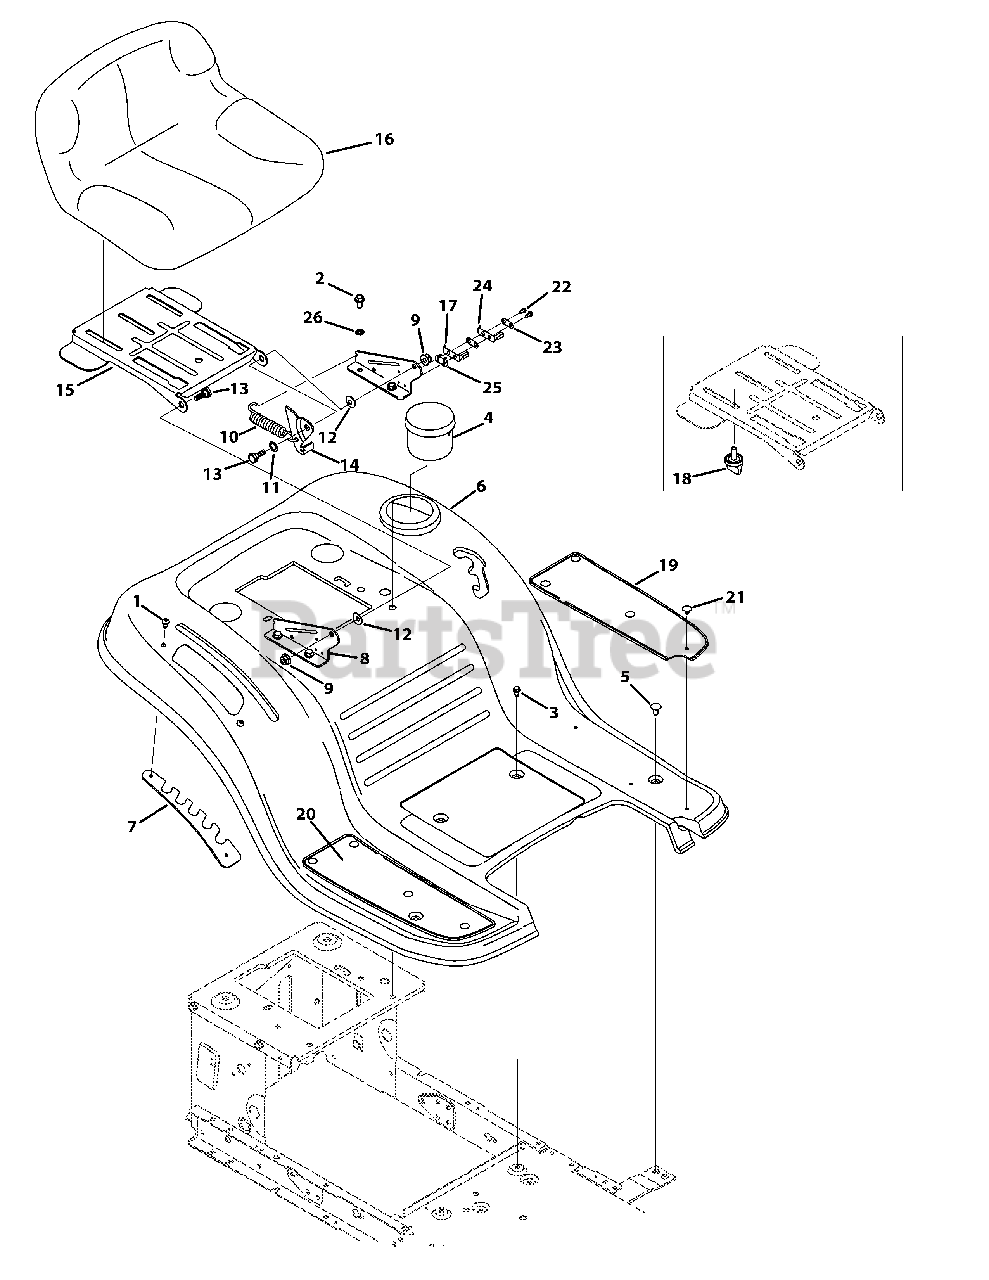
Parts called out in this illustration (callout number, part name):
1	Screw, 1/4-20 x .500
2	Screw, 5/16-18 x .750
3	Screw Pan Torx Head, 1/4-20 x .500
4	Cup Holder
5	Screw Carriage, 1/4-20 x .62
6	Fender - Orange
7	Lift Adjuster Bracket - Powder Black
8	Seat Mount Bracket - Powder Black
9	Flangelock Nut, 5/16-18
10	Extension Spring
11	Flat Washer, .510x .750 x .033
12	Bell Washer, .340 x .872 x .060
13	Shoulder Screw, 5/16-18 x .437 x .268
14	Lift Seat Bracket
15	Pivot Seat Manual Adjust Bracket
16	Med. Back Seat, Black
17	Inner Seat Spring
18	Knob, 3/8-16 x .875
19	Foot Pad, LH
20	Foot Pad, RH
21	Ratchet Clip, .250 x .500
22	Screw, 8-18 x .500
23	Insulator Plate
24	Outer Seat SPring
25	Insulator Boss Plate
26	Loack Washer, 5/16
